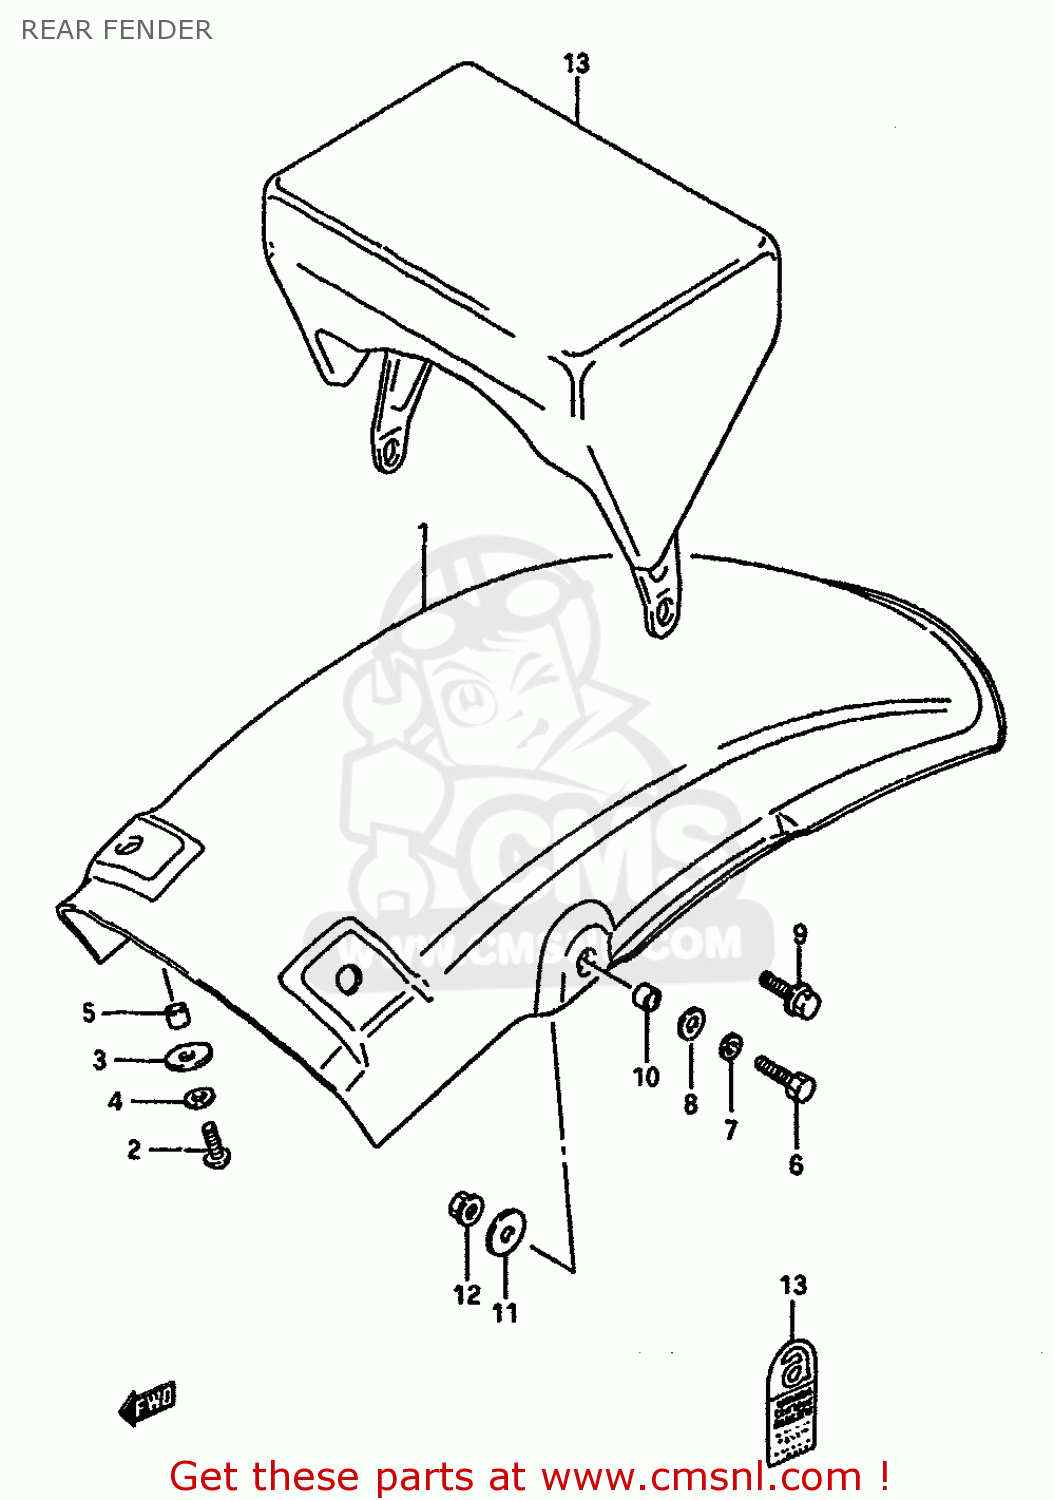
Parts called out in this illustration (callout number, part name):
1	FENDER,REAR
2	SCREW
3	WASHER
4	WASHER,LOCK
5	SPACER
6	BOLT
7	WASHER,LOCK
8	WASHER
9	BOLT 6X20
10	SPACER
11	WASHER (6.5X20X1.2)
12	NUT
13	BAG ASSEMBLY,SEAT TAIL
14	LABEL,ASBESTOS WARNING
